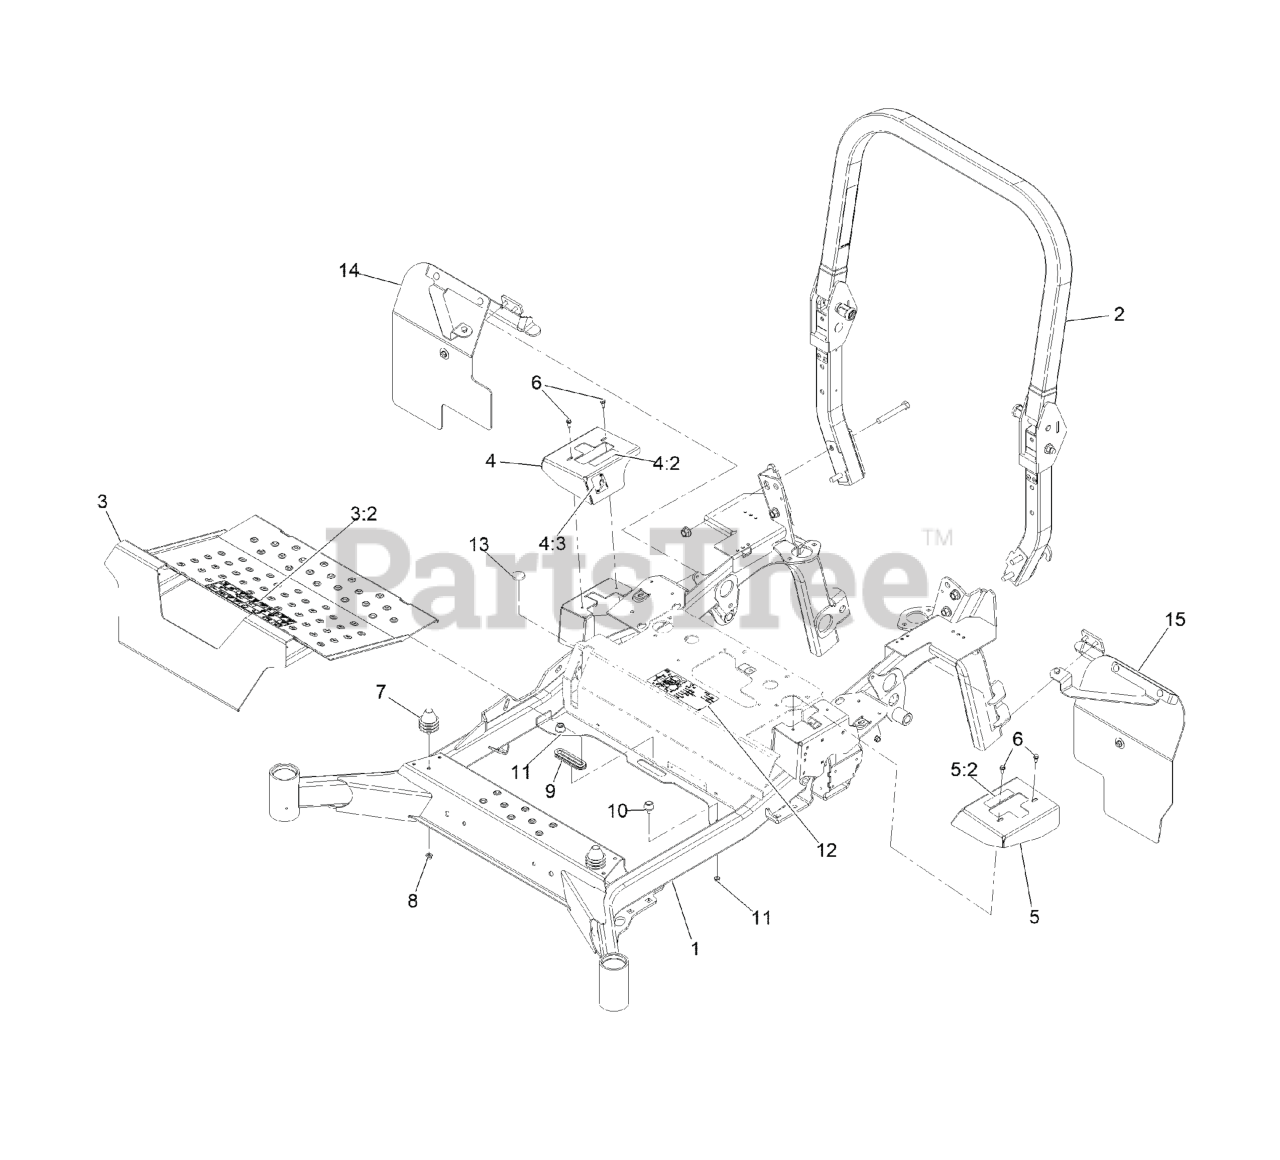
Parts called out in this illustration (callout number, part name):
1	Frame-Main
2	ROPS ASM
3	PAN-FLOOR
3:2	DECAL-DANGER
4	COVER-MOTION CONTROL, RH
4:2	DECAL-CONTROL, MOTION
4:3	DECAL-PARK BRAKE, CE
5	COVER-MOTION CONTROL, LH
5:2	DECAL-CONTROL, MOTION
6	SCREW-HWH
7	ISOLATOR
8	NUT-HF, NI
9	GROMMET-RUBBER
10	BUMPER-RUBBER
12	DECAL-SERVICE AID
13	BUMPER-PUSH-IN, RUBBER
14	ASM, RH Mud Flap
15	ASM, LH Mud Flap
